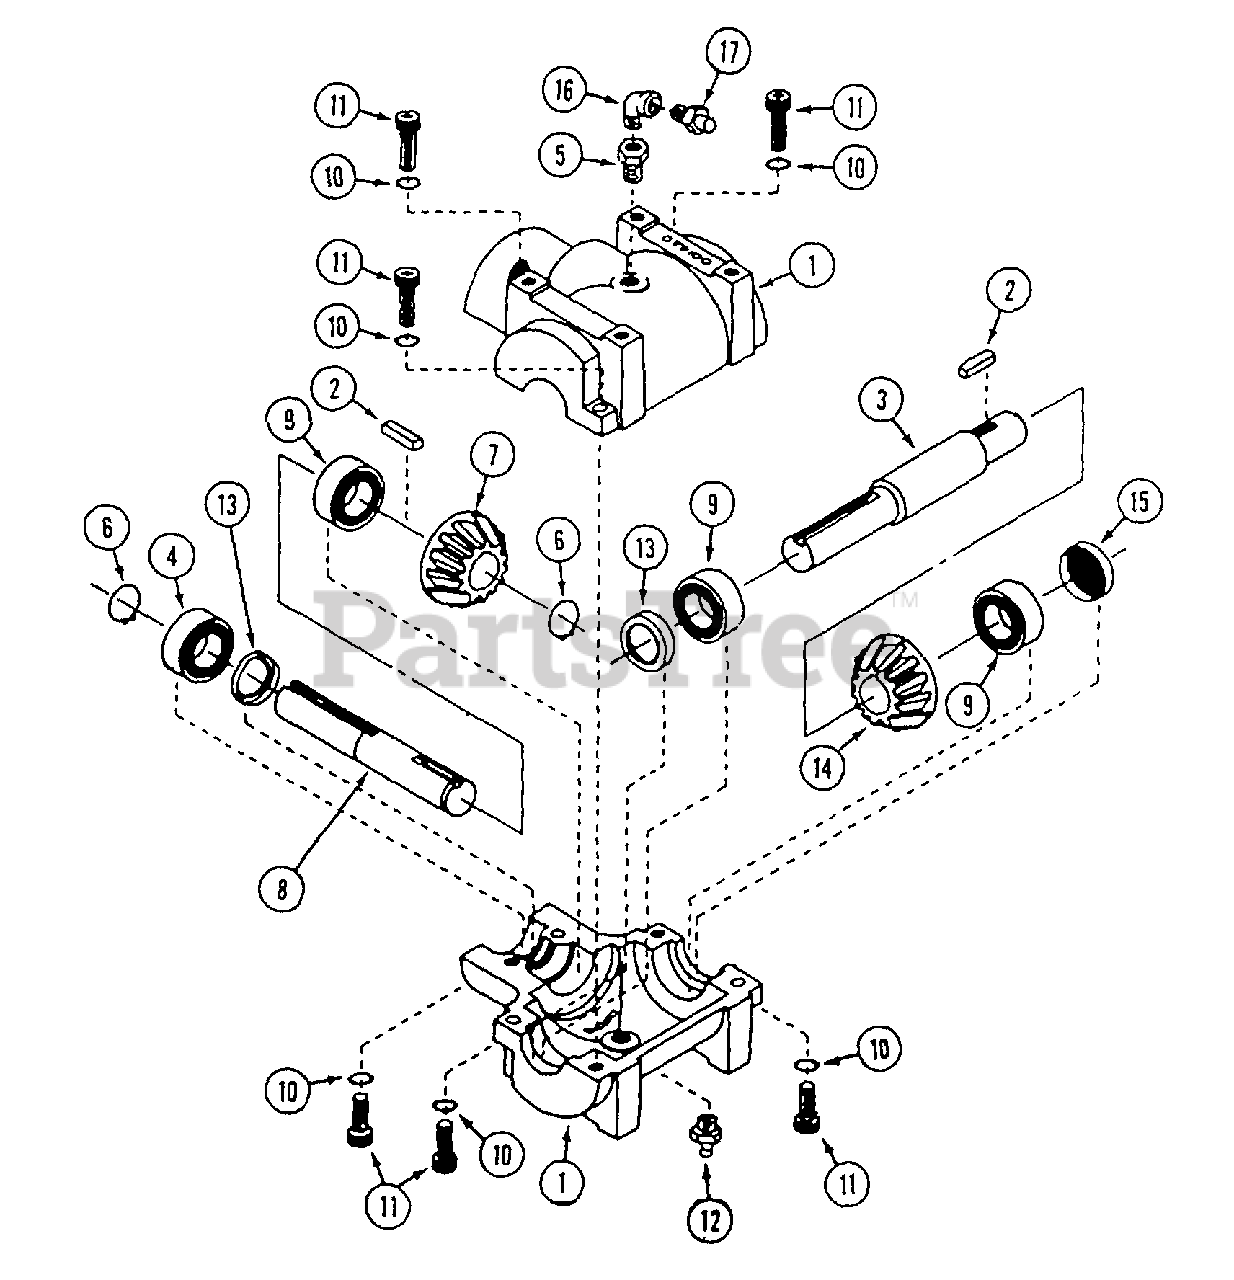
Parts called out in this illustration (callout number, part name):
1	HOUSING - half
2	KEY - 3/16" x 3/16" x 1"
3	SHAFT - input
4	BEARING - ball
5	BUSHING - pipe 1/4" x 1/8"
6	RING - retaining
7	GEAR - output shaft
8	SHAFT - output
9	BEARING - ball
10	LOCKWASHER
11	CAP SCREW - allen head
12	FITTING - grease 1/4" NPT
14	GEAR - input shaft
15	PLUG - expansion
16	ELBOW - street 1/8" x 90°.
17	VALVE - relief
